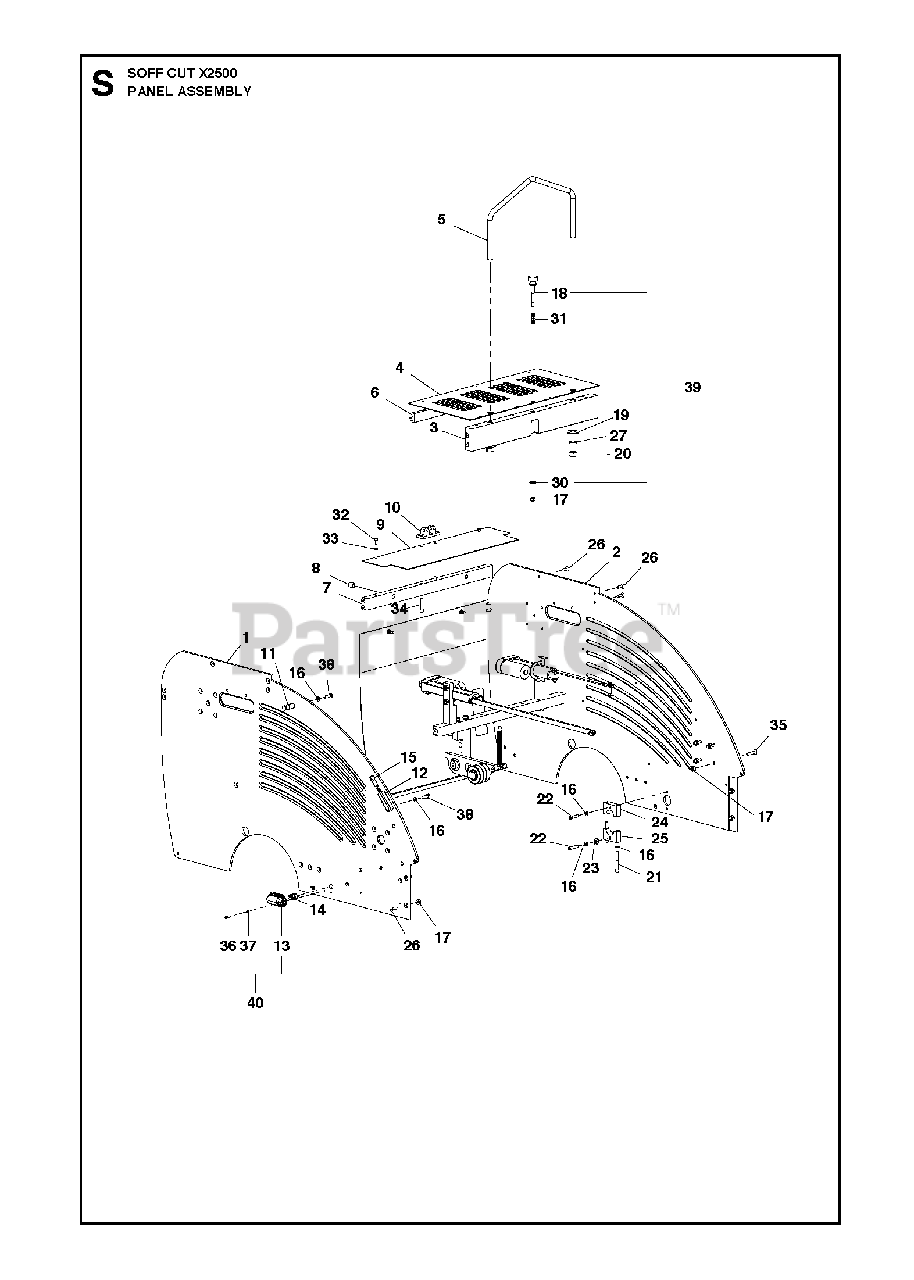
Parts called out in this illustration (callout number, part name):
7	CROSS BAR (REAR ACCESS PANEL)
9	PANEL. COVER (HANDLE ACT. CROS
17	NYLOC NUT 1/4-20 CAD PL.
30	FLAT WASH 1/4 PFC9 SAE ZINC
